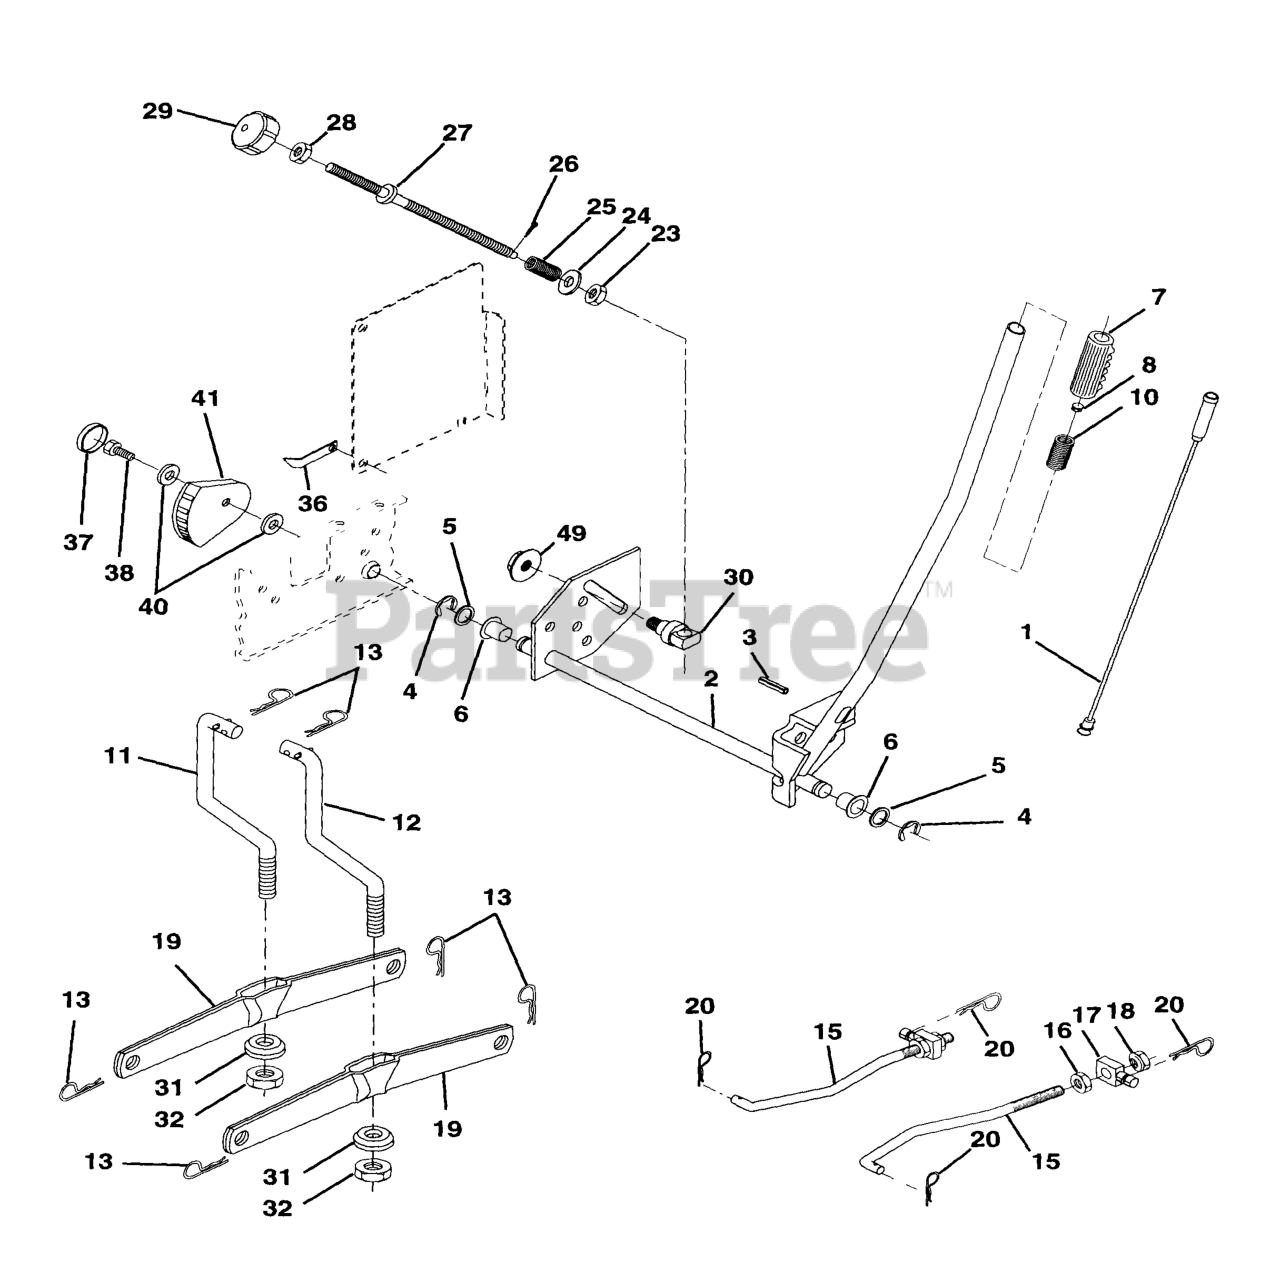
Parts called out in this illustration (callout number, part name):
1	WIRE.INNER.HANDLE.LIFT.LEVER
2	SHAFT ARM LIFT RH
3	PIN GROOVE.
4	RETAINING RING LT
6	BEARING.NYLON
7	GRIP HANDLE
8	PLUNGER BUT KIT
10	SPRING, COMP T
11	LINK LIFT LH
12	LINK LIFT RH
13	RETAINER-SPRNG RB
15	FRONT LINK
16	NUT.HEX.JAM.1/2-13
17	TRUNION
18	NUT.LK.W/WSH.1/2.
19	ARM.REAR.SUSPENSION
20	SPRING RETAINER
25	SPRING**
26	COTTER PIN
27	ROD ADJ LIFT
28	NUT
29	KNOB INF 3/8-16
31	BEARING PIVOT
32	NUT CROWNLOCK 3/8-24
36	POINTER, HEIGHT INDICATOR(2 2)
38	SCREW.THDROL.5/16-18X3/4.TTY
41	IND. HEIGHT STLT
49	NUT
